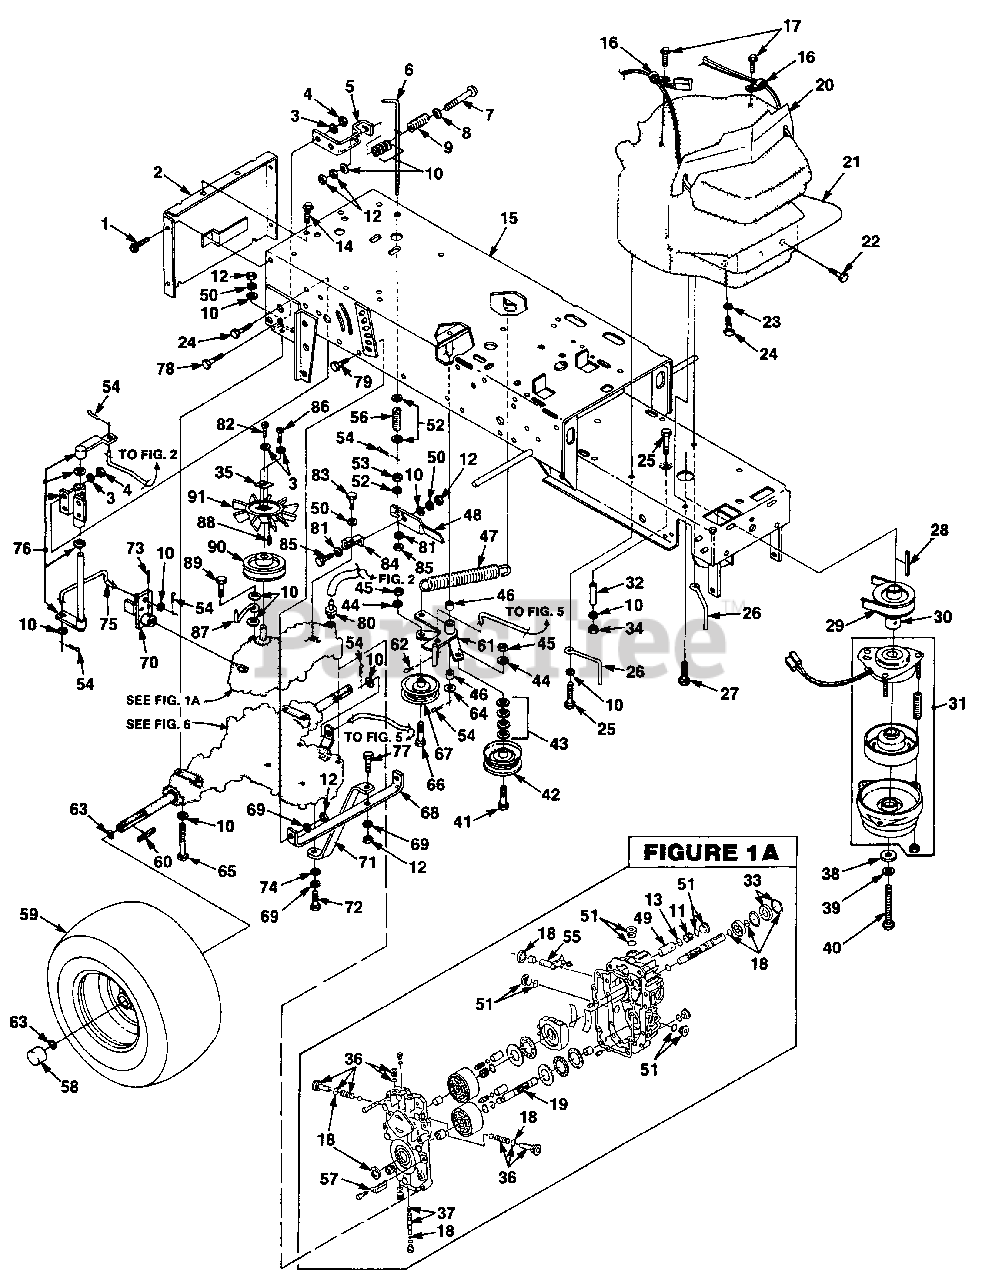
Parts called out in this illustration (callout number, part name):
1	SCREW- (1/4-14 x 1")
2	BRACKET- Hitch
3	WASHER- Lock (1/4")
4	NUT- Hex (1/4-20)
5	LIMITER- Bracket
7	BOLT- Rd.Hd.Sq. Neck (1/4-20 x 4 1/2")
8	WASHER (7/16")
9	SPRING- Compression
10	WASHER- Flat (5/16")
11	SPRING (Filter)
12	NUT- Hex (5/16-18)
13	WASHER (Filter)
14	SCREW- (1/4-20 x 9/16")
17	SCREW- Hex (#10-16 x 1/2)
18	OVERHAUL- Seal Kit
19	SHAFT- Motor
20	SHIELD
21	BULKHEAD
22	BOLT- (1/4-14 x .44)
23	WASHER- Lock (1/4-20)
24	SCREW- (1/4-20 x 5/8") (YT-15)
25	SCREW- (5/16-18 x 1/4")
26	GUIDE- Front Belt
27	SCREW- (5/16-18 x 1 3/4")
30	PULLEY- Drive
31	CLUTCH- Brake
34	NUT- Lock (5/16-18)
35	PLATE- Retainer
36	CHECK VALVE KIT
37	BYPASS VALVE KIT
38	CLUTCH- Retainer
39	WASHER- Lock (7/16")
40	SCREW- (7/16-20 x 3)
41	SCREW- (3/8-16 x 2)
42	IDLER- Inside
43	WASHER- Flat (3/8")
44	WASHER- Lock (3/8")
45	NUT- Hex (3/8-16)
47	SPRING- Extension
48	LINK- Dump
50	WASHER- Lock (5/16")
52	WASHER- Flat (1/4")
53	NUT- Lock (1/4-20)
54	PIN- Cotter (3/32-3/4")
55	UNION ARM
57	NAME PLATE
58	CAP- Rear Hub
59	REAR WHEEL ASSY
60	KEY- (1/4 x 2.50)
61	BEARING ASSY.
63	RING- Snap
64	WASHER- Flat (1/2")
65	SCREW- (5/16 x 3")
66	SCREW- (3/8-16 x 1 3/4")
68	REINFORCEMENT
69	WASHER- Lock (5/16")
70	ARM & LUG
71	BRACKET- Rotation Control
72	SCREW- (5/16-18 x .88)
73	SCREW- Set (1/4-20 x 1/2")
74	WASHER- Flat (5/16")
76	PIVOT- Bracket & Arm
77	HEX BOLT- (5/16-18 x 1")
78	SCREW- (1/4-20 x 3/4")
79	SCREW- (5/16-18 x 3/4")
80	CONNECTOR
82	SCREW- (m6 x 1 x 12mm)
83	SCREW- (m8 x 1.25 x 50mm)
84	BRACKET- Pivot
85	SCREW- (5/16-18 x 7/8")
86	SCREW- (10-24 x 5/8")
87	GUIDE BELT
89	SCREW- (m8 x 1 1/4 x 120mm)
